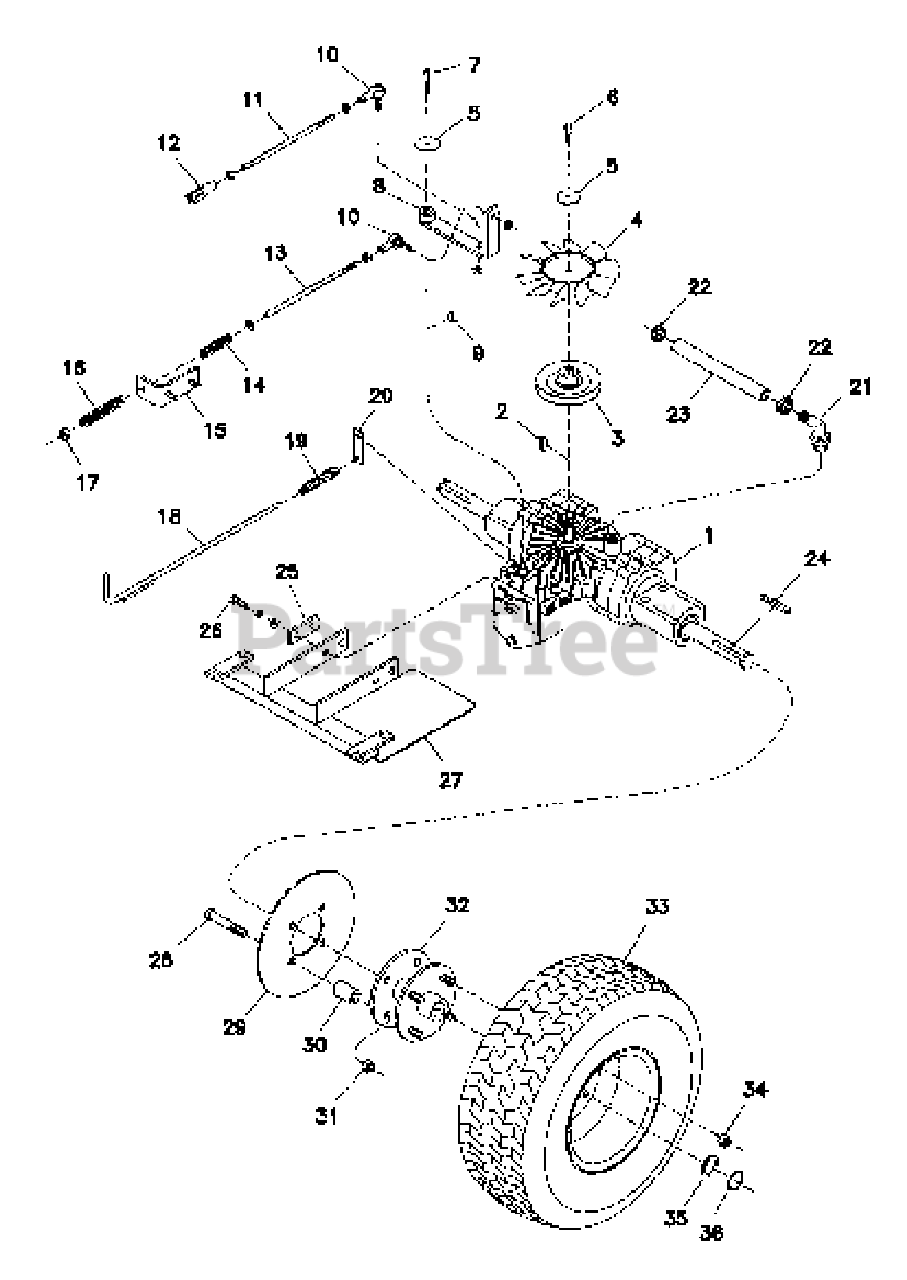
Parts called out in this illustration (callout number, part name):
1	TRANSMISSION, Hydrostatic
2	KEY, Woodruff
3	PULLEY, Transmission Input
4	FAN
5	RETAINER, Fan
6	CAPSCREW, Allen Head w/Loctite Patch, 1/4-20 x 1-3/4
7	CAPSCREW, Allen Head w/Loctite Patch, 1/4-20 x 1-1/2
8	CONTROL ARM
9	KEY, Woodruff
10	BALL JOINT, 5/16
11	HYDRO LINKAGE ROD
12	CLEVIS, Plastic, 5/16
13	NEUTRAL LINKAGE ROD
14	SPRING, Compression
15	NEUTRAL BRACKET
16	SPRING, Compression
17	COLLAR, 5/16 Set
18	TRANSMISSION RELEASE ROD
19	SPRING, Extension
20	RELEASE VALVE EXTENSION
21	FITTING, 90 deg.
22	HOSE CLAMP
24	KEY, 1/4 x 2-1/2
25	SUPPORT, Mount
26	CAPSCREW, Hex Head, 5/16-18 x 1
27	TRANSMISSION MOUNT
28	CAPSCREW, Hex Head, 1/2-20 x 3
29	BRACKE DISC
30	HUB SPACER
31	NUT, Hex, Nylon Lock, 1/2-20
32	DRIVE HUB
33	DRIVE TIRE
35	SHIM
36	SNAP RING
